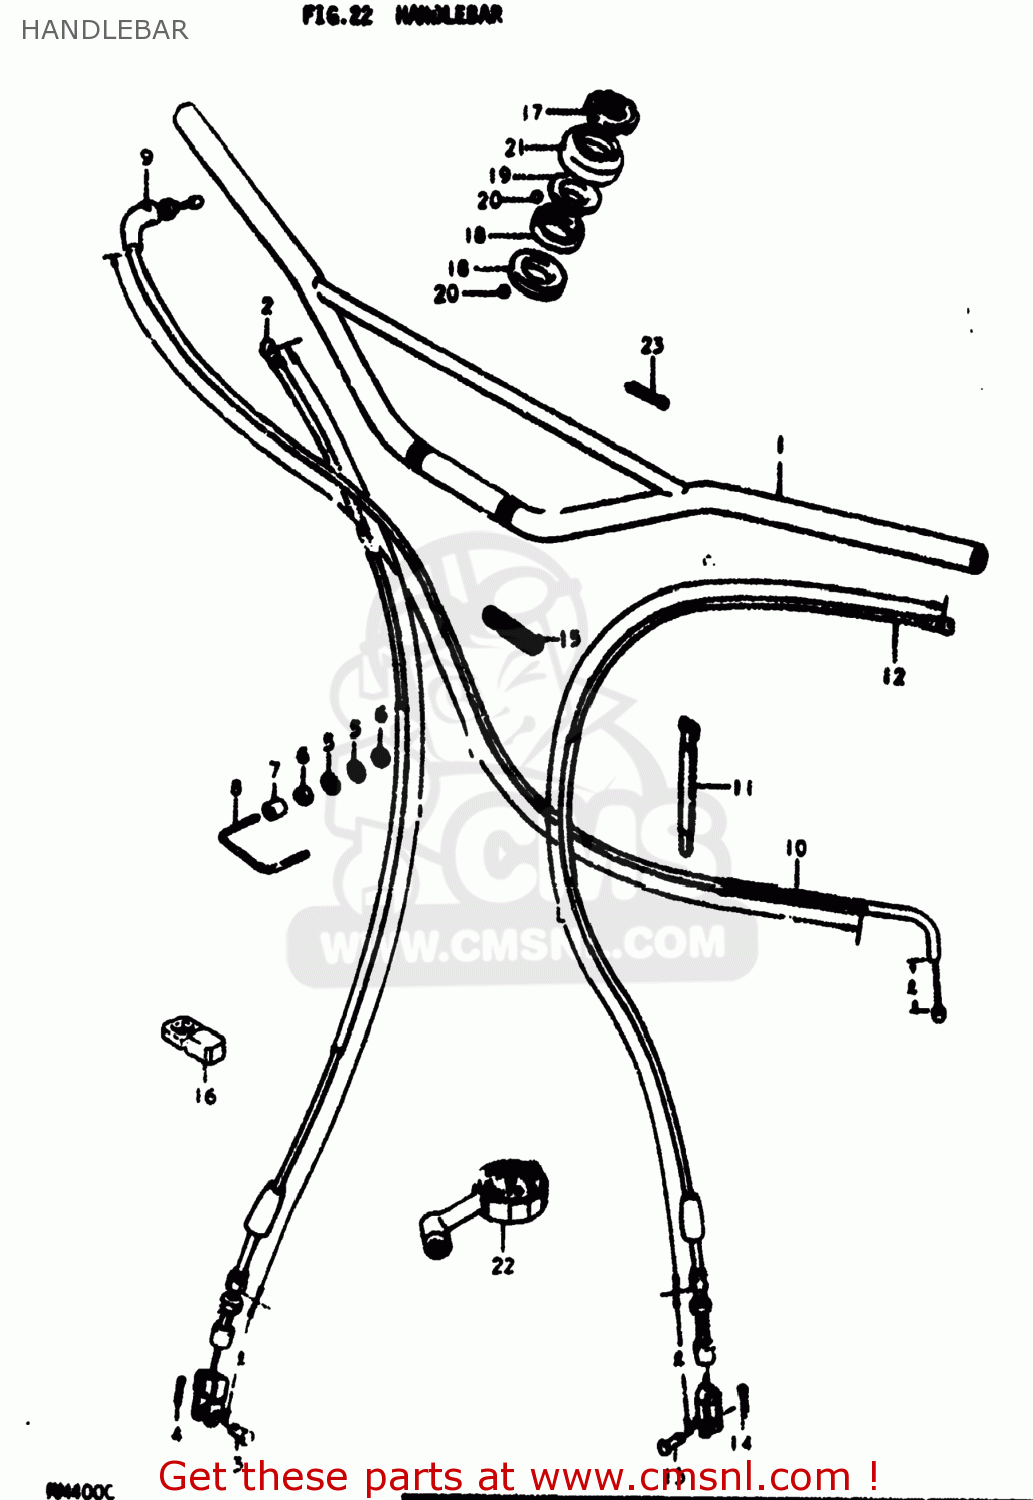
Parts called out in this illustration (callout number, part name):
1	HANDLEBAR
2	CABLE ASSEMBLY,FRONT BRAKE
3	PIN(L:17.5)
4	PIN
5	WASHER
6	NUT
7	BUSHING
8	CLAMP,CABLE
9	CABLE ASSEMBLY,THROTTLE
10	PROTECTOR,CABLE
11	CLAMP
12	CABLE ASSEMBLY,CLUTCH
13	PIN(L:13)
14	PIN
15	CLAMP L:35
16	GUIDE,CABLE
17	NUT,STEERING STEM(25X44X10)
18	LACE,STEERING INNER LWR
19	LACE,STEERING OUTER UPR
20	BALL
21	DUST SEAL,STEERING UPR
22	GAUGE ASSEMBLY,AIR PRESSURE
23	COTTER PIN
